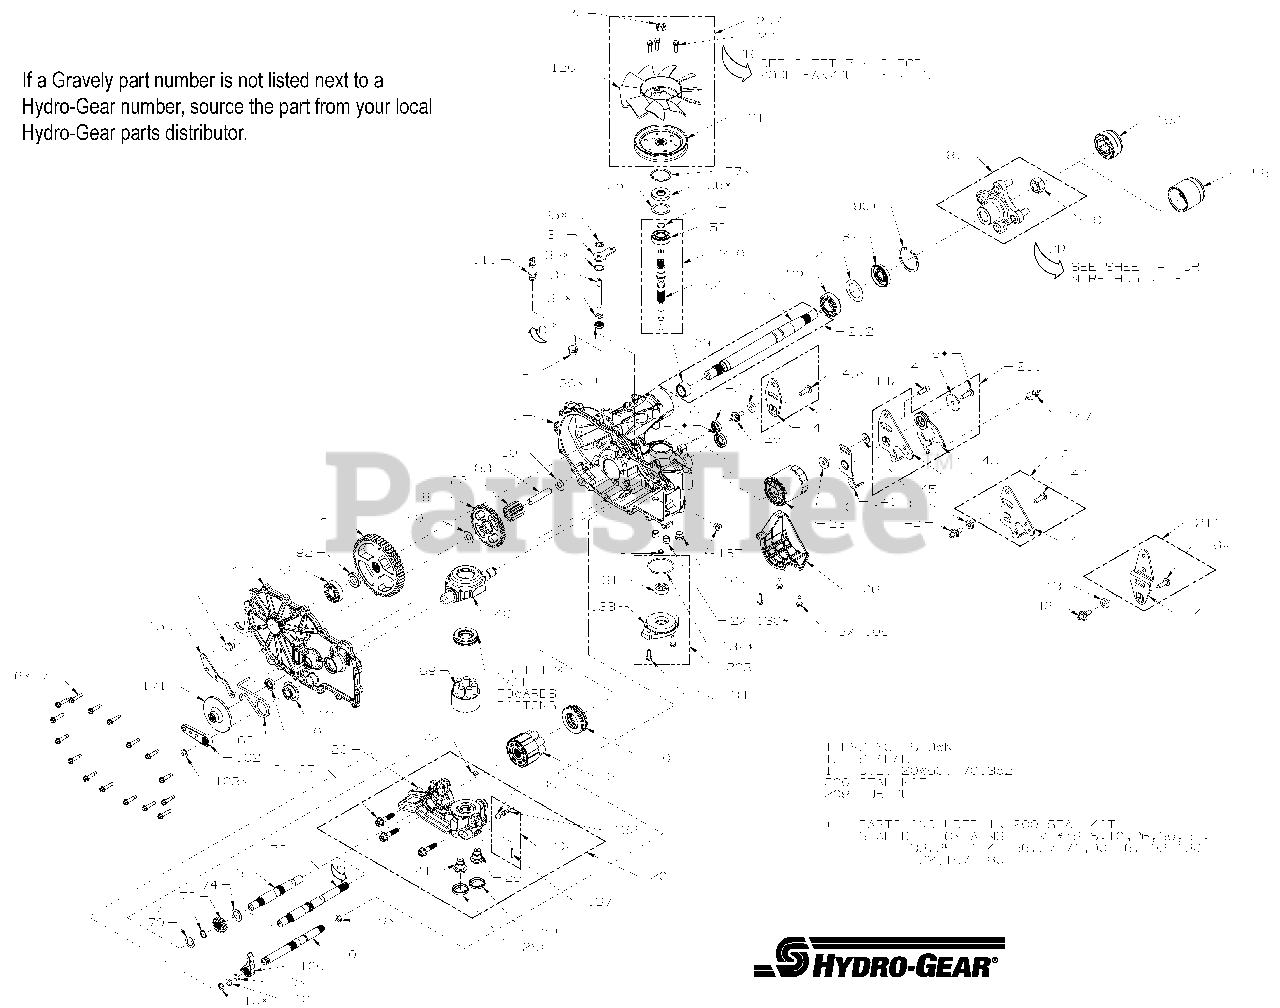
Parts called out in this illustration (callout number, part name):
1	KIT, HOUSING, MAIN, LH, CHRG, CNTL
2	KIT, COVER, SIDE, LH
7	SCREW,HEX WASHER 1/4-20X1.125
13	SEALANT TUBE 10.1OZ.
22	PLATE, BYPASS
23	OIL FILTER, TRANSMISSION
26	SEAL, PLUG 1.375 X .250
30	SEAL, LIP .375X.75X.25
31	RING. RETAINING
32	ROD, BYPASS
33	RING, RET .750
34	HG BYPASS ARM (52370)
35	RING, RTNG .
40	TRUNNION, SWASHPLATE
41	SEAL, LIP 18X32X7
45	WASHER
46	TWHCS 5/16-24 X 1.00
55	WASHER 1.23X1.56X.04
56	SEAL, LIP 17X40X7
57	RING, RET 1.56 INT
60	HG THRUST BEARING (51462)
64	HG 16CC CYLINDER BLOCK (71579)
65	BEARING. THRUST 30 X 52 X 13
69	ASSY, BLOCK 7 PISTON
70	WASHER .63X1.0X.05
71	RING, RET 62 EXT
73	SHAFT, MOTOR
74	WASHER .71 X 1.16 X .04
80	WASHER .5X1.0X.032
83	JACK SHAFT (PIN)
90	RING, RETAINING
95	BEARING, BALL 25.4 X 52 X 15
96	SEAL, LIP
97	KIT, HUB 4 BOLT
99	NUT, HEX, LOCK 3/4-16
100	JPAWL, BRAKE
101	SHAFT, BRAKE
102	BRAKE ARM HYRDROGEAR 52499
103	RING, RETAINING
105	HFHCS 1/4-20X.75
106	HG FILTER GUARD LH (52247)
111	KIT, FITTING 1/2 BEADED 9/16
120	FAN, 7.0 W/INSERT
121	DISC, PULLEY, CUPPED, 4.5 INCH
122	NUT, HEX 1/2-20 PATCH
124	HUB, PULLEY
130	TUBE, CONNECTING
131	GEROTOR
132	O-RING HYDROGEAR 52250
133	COVER, CHARGE PUMP
134	HFHCS 1/4-20X.75
140	SPACER
141	ARM, NEUTRAL LEFT
142	SHCS 5/16-24X1 PATCH
147	SPRING, HYDROGEAR P/N 51833
157	KIT, GEROTOR SEAL
158	CAP, AXLE
186	TUBE, AXLE
200	KIT, SEAL
201	KIT, CENTER SECTION, LH, CHRG
202	KIT, CHARGE RELIEF
203	KIT, CHARGE
207	KIT, FAN/PULLEY
209	HUB PULLER 4 BLT HYDGEAR 71459
210	INPUT SHAFT 2800 HYDGEAR 71442
211	KIT, RTN, CCW
212	KIT, SHAFT, AXLE
